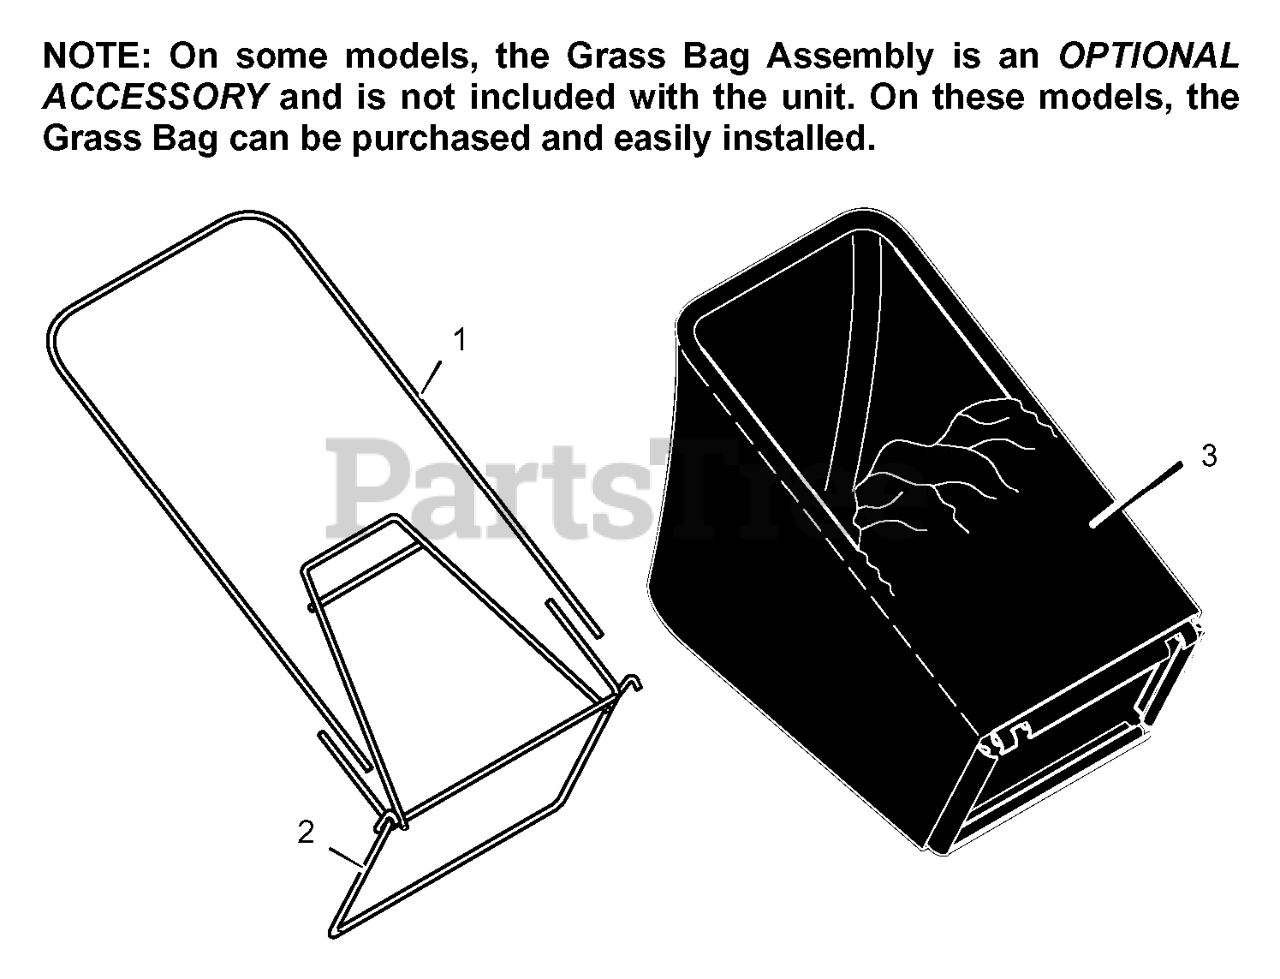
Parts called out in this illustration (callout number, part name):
1	Frame, Top
2	Frame Assembly
3	Bag, Cloth - Black
3	Bag, Cloth - Gray
